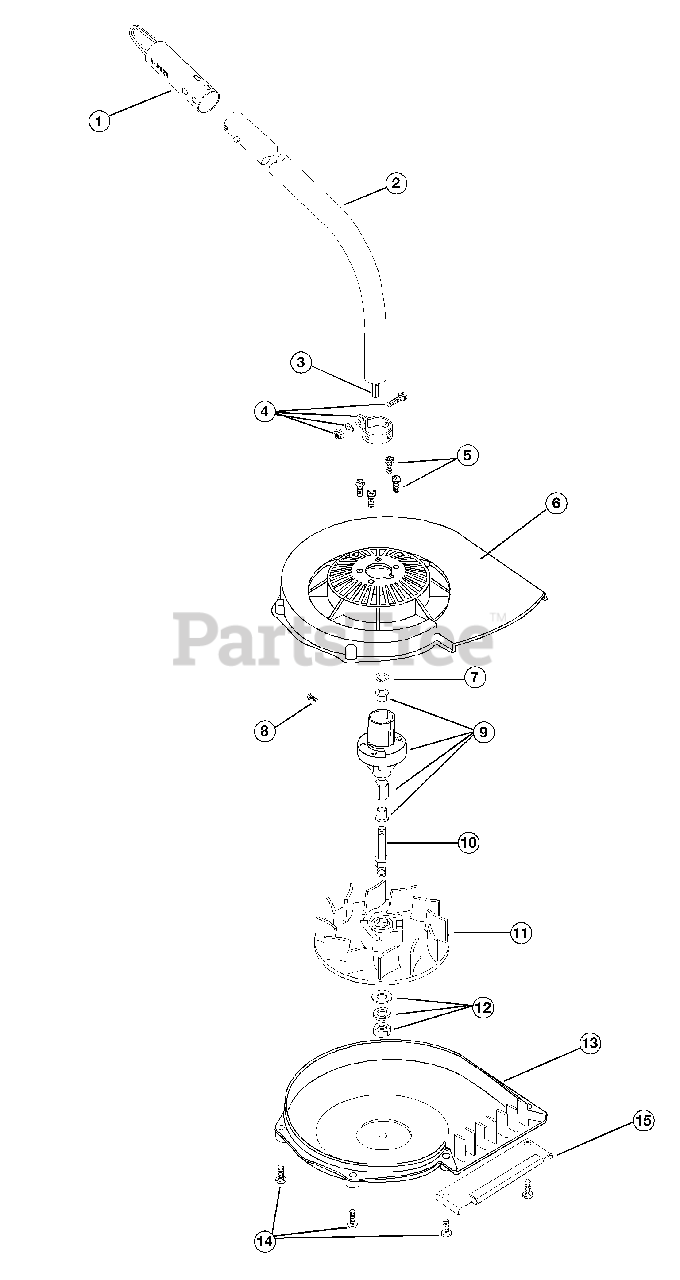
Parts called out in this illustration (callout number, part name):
1	Hanger
2	Drive Shaft Housing Assembly
3	Drive Shaft Assembly
4	Lower Clamp Assembly
5	Mounting Screw Assembly
6	Upper Housing Assembly
7	Palnut
8	Anti-Rotation Screw
9	Bushing Housing Assembly
10	Impeller Shaft
11	Impeller
12	Nut and Washer Assembly
13	Lower Housing Assembly
14	Mounting Screw Assembly
15	Edge Guard
